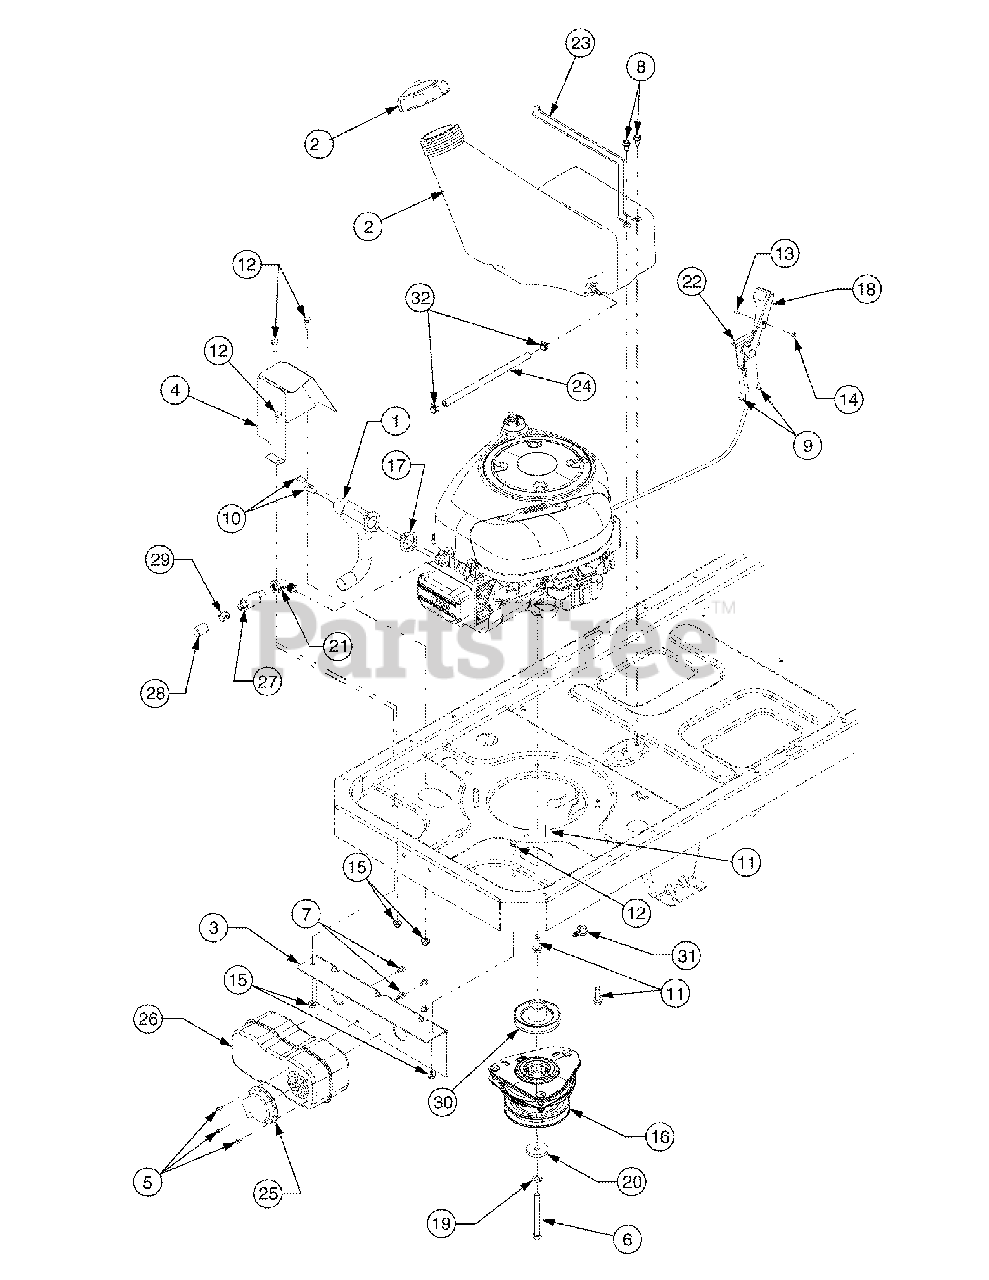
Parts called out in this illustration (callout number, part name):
1	Tube, Exhaust
2	Tank, Fuel, 3.0 Gal.
2	Cap, Fuel
3	Bracket, Muffler Mounting
4	Shield, Muffler Tube Heat
5	Screw, Hex Wash. Hd. Tapp #8-18 x .5
6	Screw, Hex Cap, 7/16-20 x 4.0 GR5
7	Screw, Hex Wash. Hd. Tapp 1/4-20 x .5
8	Screw, Hex Wash. Hd. Tapp 5/16-12 x .75
9	Screw, Hex Wash. Hd. Tapp #12-16 x .5
10	Screw, Socket Hd. 5/16-18 x .75
11	Screw, Hex Wash. Hd. Tapp 3/8-16 x 1.25
12	Screw, Hex Cap, 5/16-18 x .75 GR5
13	Screw, Truss Hd. Mach. #8-32 x .375
14	Nut, Hex, #8-32
15	Nut, Hx Insert Flange Lck, 5/16-18 GrF
16	Clutch Assembly, Electric PTO
17	Gasket, Exhaust (272293)
18	Knob, Throttle Control
19	Washer, Lock, 7/16
20	Washer, Flat, .438 x 1.75 x .25
21	Fitting, Elbow
22	Cable, Throttle, 39.0 Lg
23	Wire, Tank Mounting
24	Hose, Fuel Line
25	Deflector, Muffler
26	Muffler
27	Valve, Oil Drain
28	Hose, Oil Drain Extension
29	Cap, Oil Drain Valve
30	Pulley, Drive
31	Clip, Cable Retainer
32	Clamp, Hose
